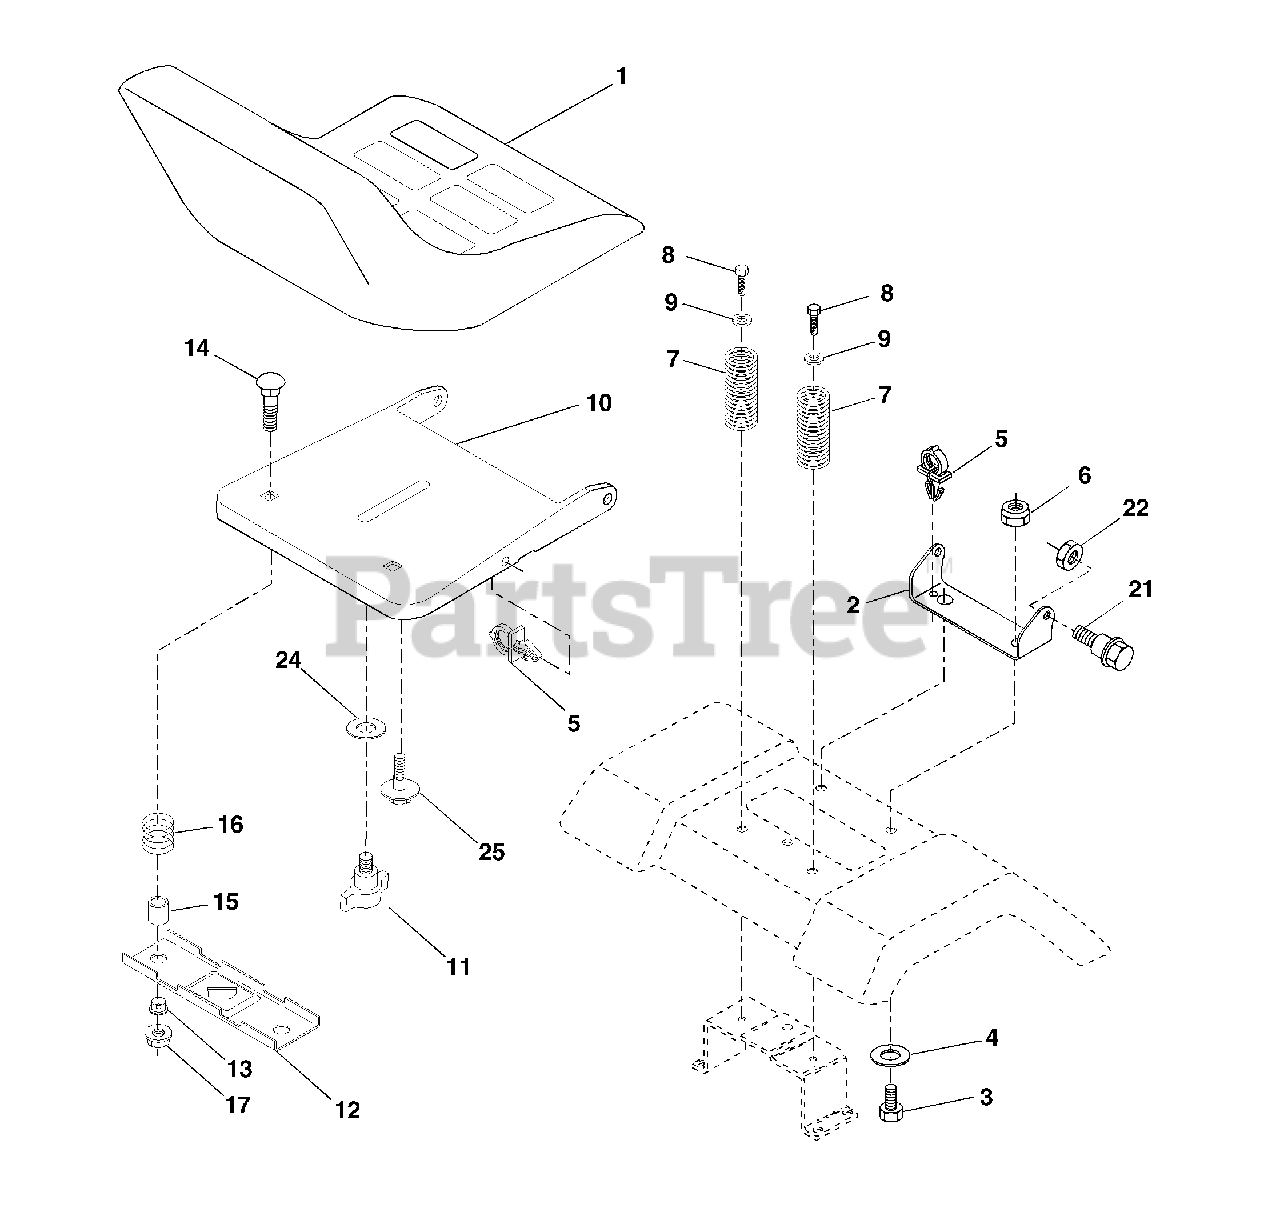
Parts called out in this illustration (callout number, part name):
1	Seat
2	Bracket Pivot Seat 8 720
3	Bolt Fin Hex 3/8-16unc X 1
4	Washer 13/32 X 1 X 10 Ga
5	Clip Push-In
6	Nut Hex w/Ins. 3/8-16 Unc
7	Spring Seat Cprsn 2 250 Blk Zi
8	Screw 3/8-16 X 1
9	Washer 13/32 X 1 X 14 Ga.
10	Pan Seat
11	Knob Seat Adj Wingnut
12	Bracket Mounting Switch
13	Bushing Snap Blk Nyl 50 Id
14	Bolt Rdhd Sqnk 1/4-20x1-1/2
15	Spacer Split 28x 96 Yel Zinc
16	Spring Cprsn 1 27 Blk Pnt
17	Nut Lock 1/4 Lge Flg Gr 5 Zinc
21	Bolt Shoulder 5/16-18 Unc
22	Nut Hex Lock W/Ins 5/16-18
24	Washer 17/32 X 1-3/16 X 12 Ga.
25	Bolt Shoulder 5/16-18 X 62
